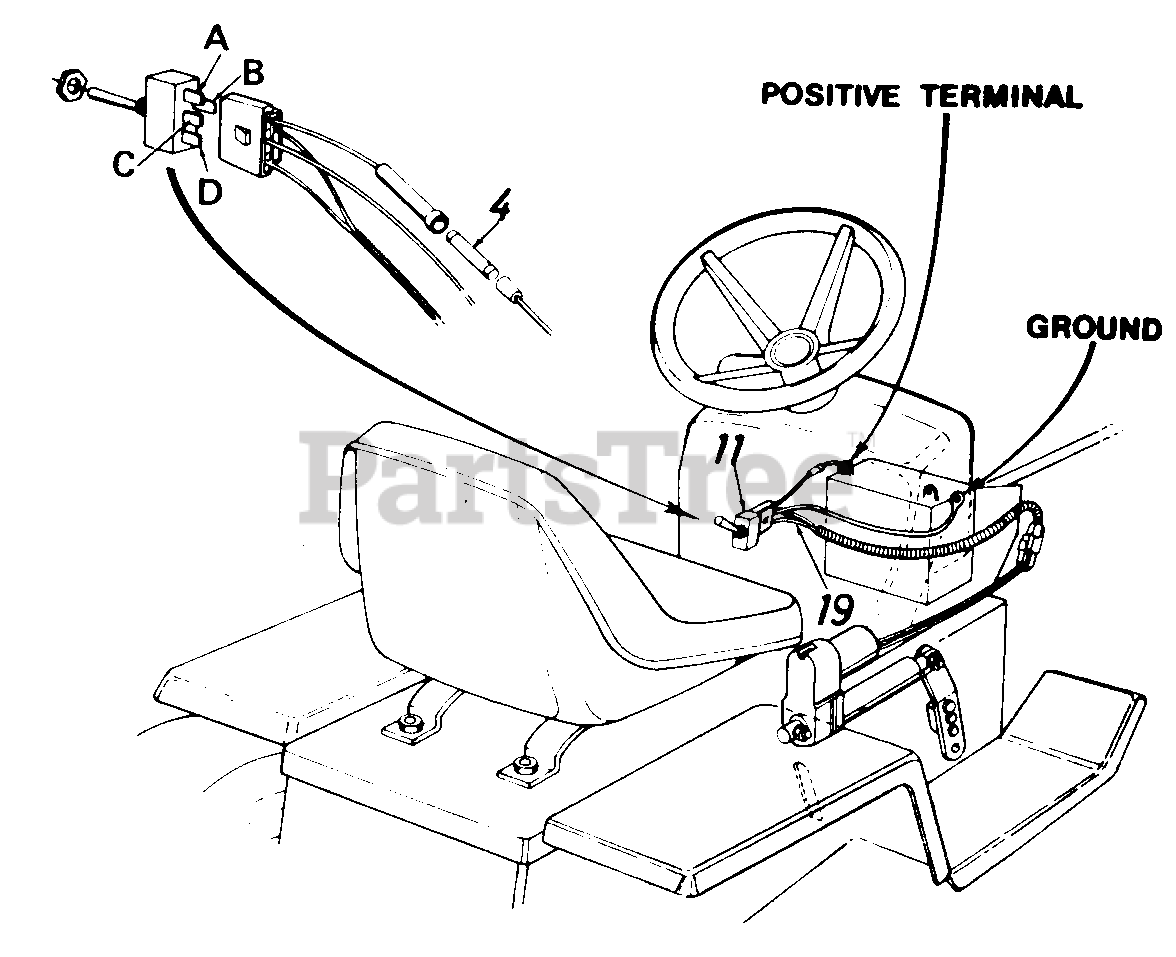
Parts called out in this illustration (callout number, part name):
4	Fuse 30 AMP
11	Toggle Switch
19	Wire Harness
A	Blue Wire-Connects to Positive Terminal on Battery
B	Yellow Wire-Connects to Actuator
C	Black Wire -Ground Wire-to Frame
D	Red Wire -Connects to Actuator
